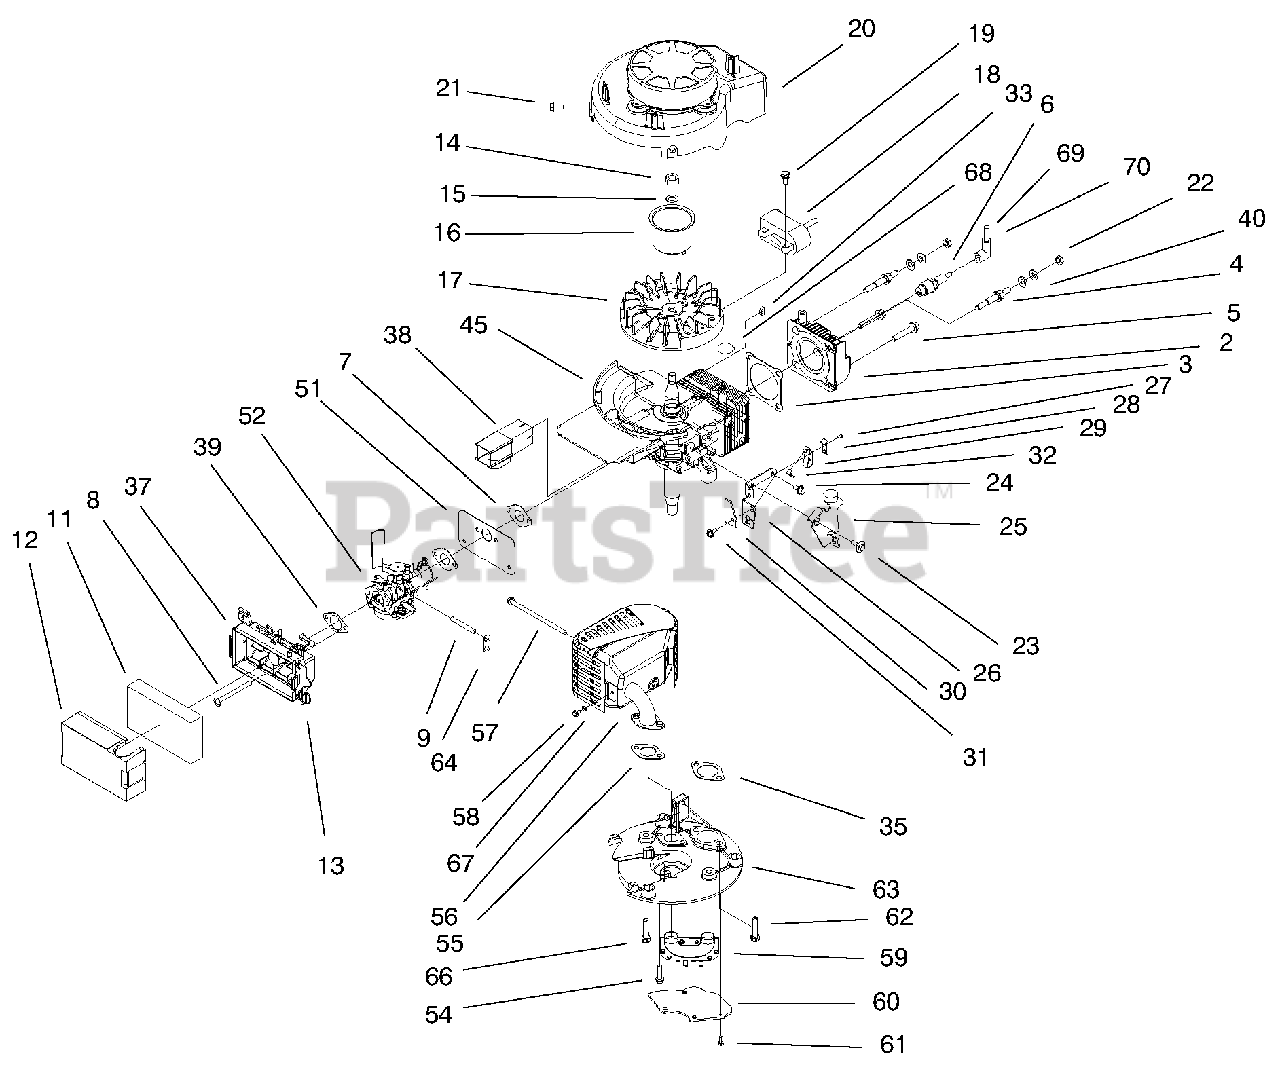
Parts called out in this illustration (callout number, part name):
3	Gasket-Head
6	Spark Plug
7	Intake Gasket
9	Primer Hose
11	Element-Air Filter
12	Cover-Air Filter
13	Retainer-Filter
15	Washer-Lock
16	Cup-Starter
17	Flywheel Machined Recoil
18	Ignition ASM
19	Screw-HWH
20	Shroud & Recoil ASM
21	Screw
22	Nut-Lock
23	Shoulder Screw Brake
24	Screw (Brake)
25	ASM-Brake Plate
26	Plate-Mount Brake
27	Rivet-Self Expand Plas
28	Strap-Insulation
29	Strap-Ground
30	Stop-Ground Strap
31	Screw-Thread Forming
32	Brake Switch Lead Wire
35	Gasket-Exhaust
37	Air Filter Base ASM
39	Gasket-Filter Base
40	Washer-Lock
45	Short Block ASM Service
51	Heat Shield
52	Carburetor ASM
54	Screw-HWH
56	Muffler & Guard
59	Transfer Tube
60	Cover Plate
62	Screw-HH
63	Muffler Plate Machining
64	Retainer Hose
66	Screw-Hhd Washer
67	Washer-Lock
68	Tie Strap
69	High Tension Lead
70	Cover & Terminal
